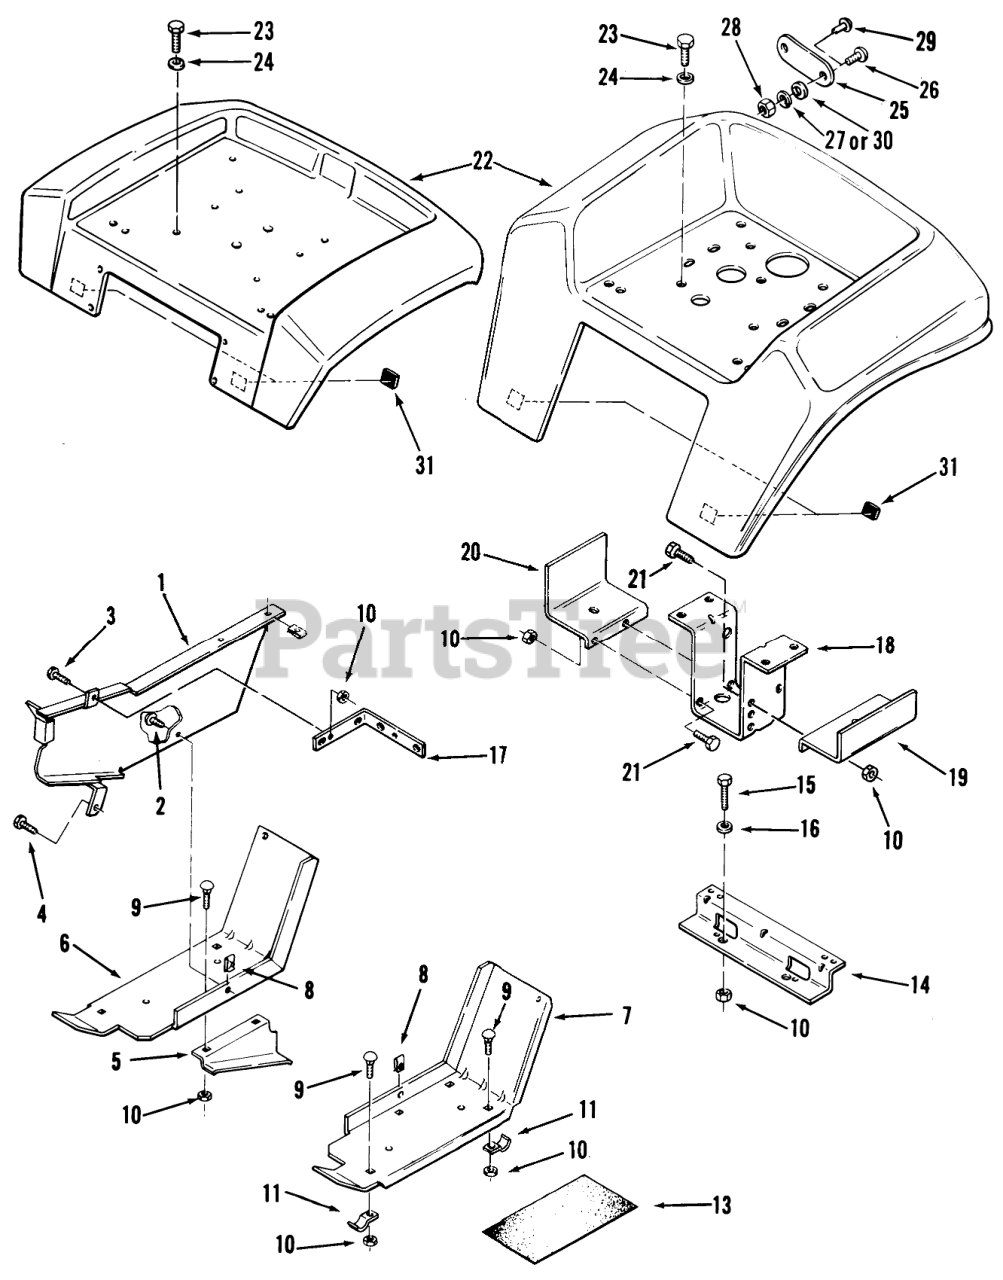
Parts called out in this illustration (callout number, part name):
1	ASSY-BELT GUARD 8 R
1	Belt Guard
2	Screw
3	Bolt
4	SCREW
5	GUID-LOWER BLTR
6	Footrest-RH
7	FOOTREST LH R
9	CARRIAGE BOLT -4
10	Nut
11	BRACKET
13	PAD-FOOTREST
14	BRACKET-FENDER B
15	Bolt
16	WASHER 5/16 SAE
17	Support Bracket-Belt Guard
18	Bracket-Fender Support
19	Fuel Tank Support LH
20	Support-FueITank RH
21	Bolt
22	Fender
23	Bolt
24	Collar
24	WASHER 5/16 SAE
25	REFLECTOR-STICK ON
26	Screw
27	Lockwasher
28	Nut
29	Poprivet
30	WASHER
31	BUMPER
